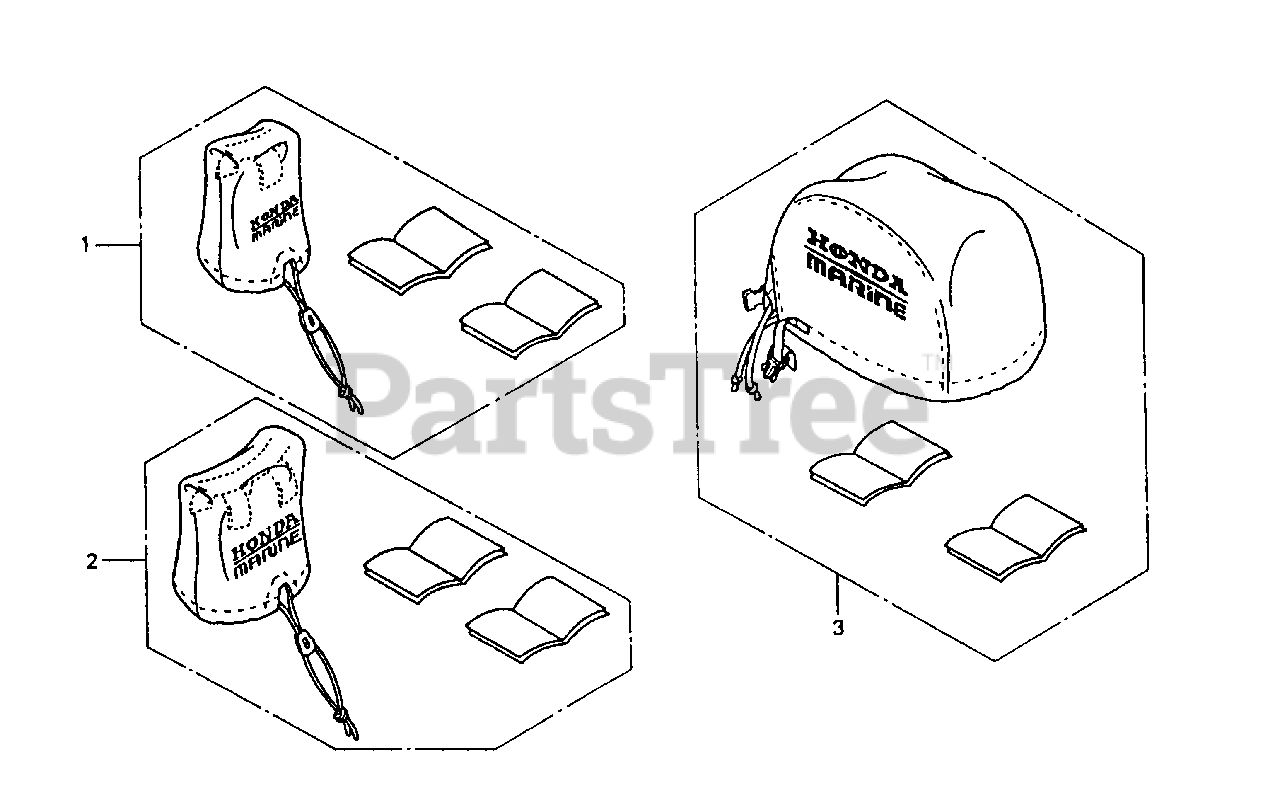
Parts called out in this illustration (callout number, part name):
1	COVER KIT, REMOTE CONTROL BOX (TOP MOUNT SINGLE)
2	COVER KIT, REMOTE CONTROL BOX (TOP MOUNT DUAL)
3	COVER KIT, ENGINE (BF75)
